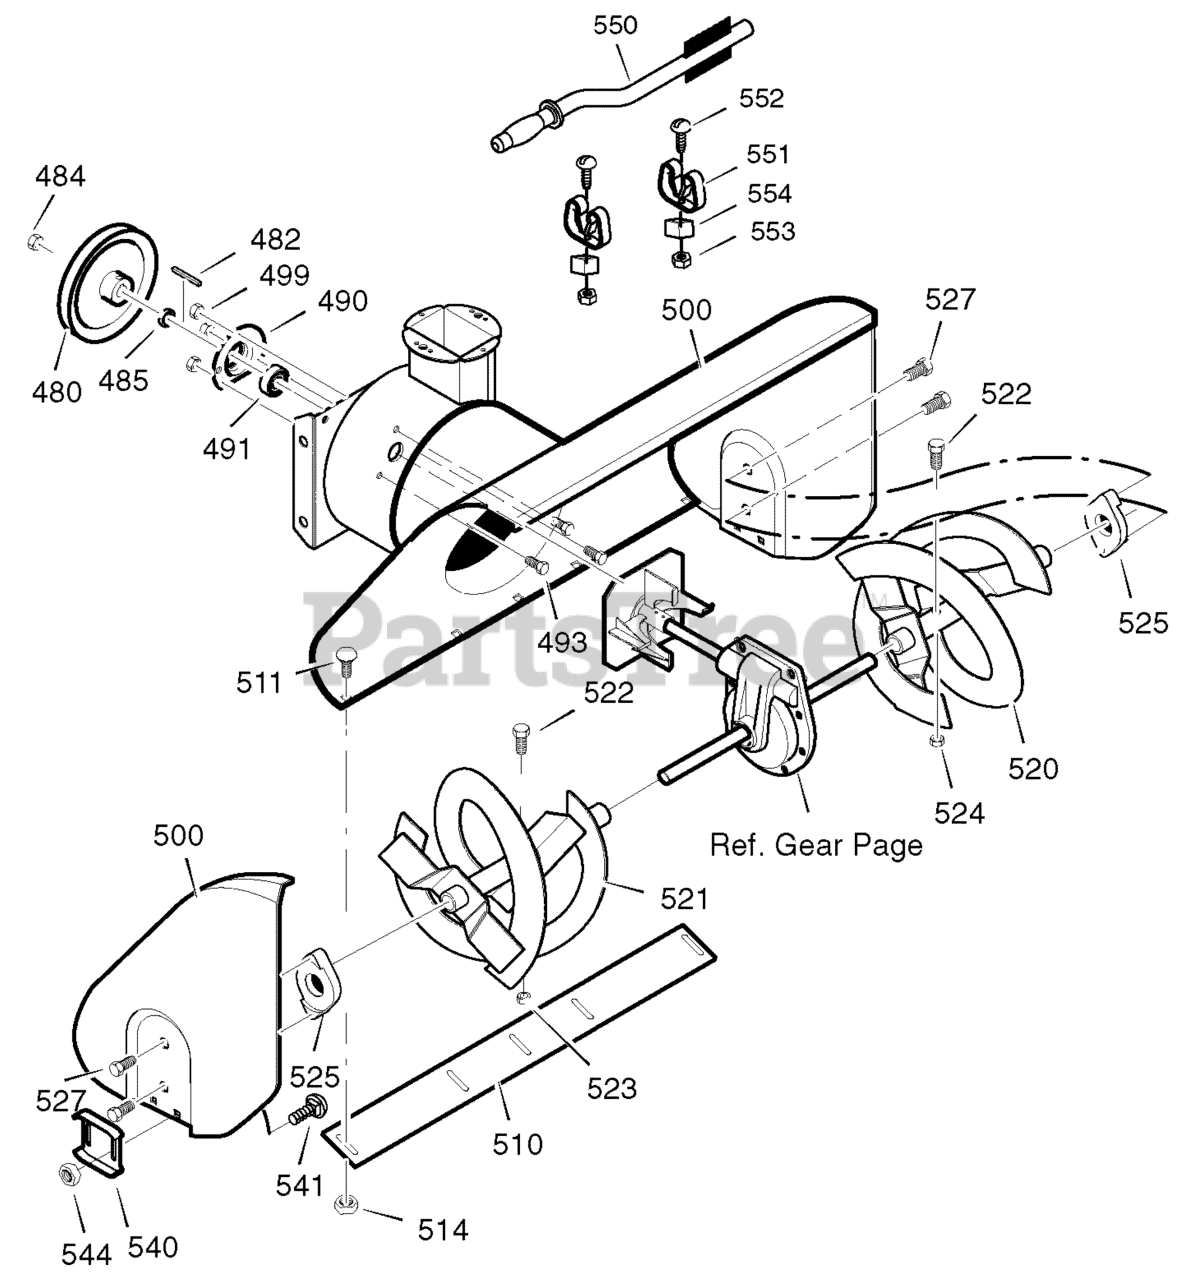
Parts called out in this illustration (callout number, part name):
480	PULLEY
482	KEY, SQUARE
484	NUT, 1/4-20
485	SPACER, FRICTION PULLEY
490	RETAINER, BALL BRNG
491	BEARING, BALL
493	BOLT, HEX - 0.31-18X0.50
499	NUT, 5/16-18 HEXWDFLLK
500	HOUSING, ASSY
510	BLADE, SCRAPER
511	BOLT, 1/4-20X.75
520	AUGER, ASSY, LH
521	AUGER, ASSY, RH
522	SCREW, 5/16-18 x 2.00
524	NUT, 5/16-18
525	BEARING,FLANGE
527	SCREW, 5/16-18 X .75
540	SKID, HEIGHT ADJUST
541	BOLT, 5/16-18 X .75
544	NUT, 5/16-18 REGHEX
550	BRUSH, CLEANOUT
551	CLIP, RETAINER
552	SCREW
554	BLOCK
